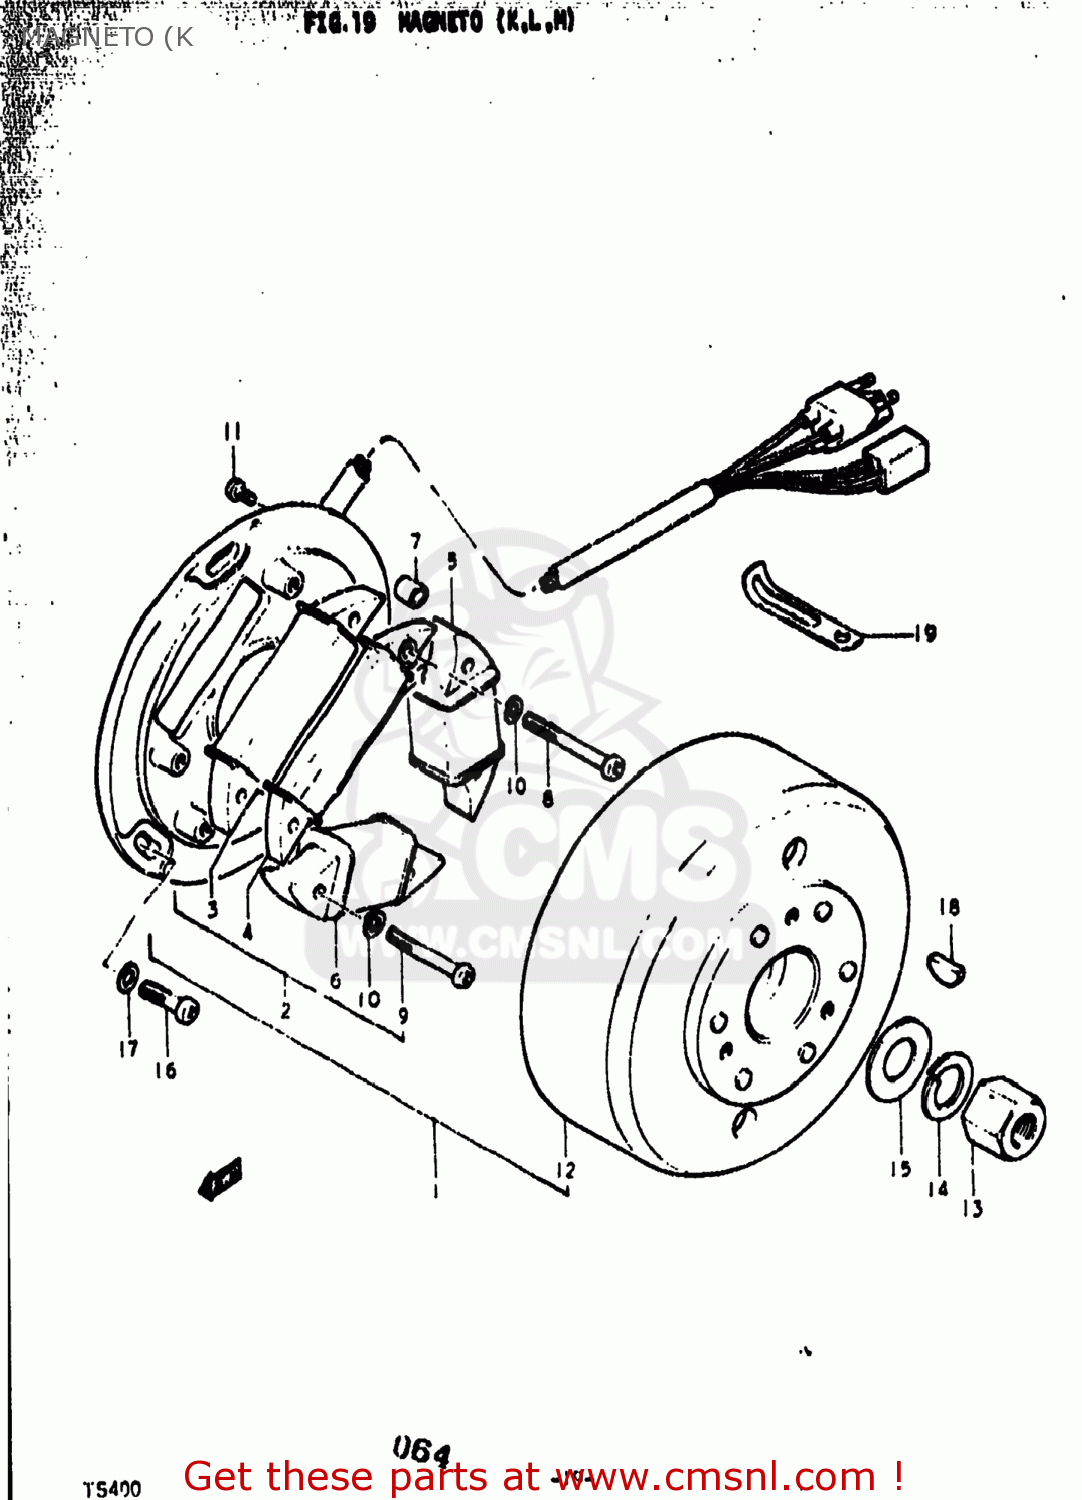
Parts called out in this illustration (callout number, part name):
1	MAGNETO ASSEMBLY
2	STATOR ASSEMBLY
3	COIL
4	COIL,PULSER
5	COIL,LIGHTING
6	COIL,LIGHTING
7	COIL ASSEMBLY,PICK-UP
8	SCREW 5X35
9	SCREW
10	LOCK WASHER
11	SCREW
12	ROTOR,FLYWHEEL
13	NUT
14	LOCK WASHER
15	WASHER(14X27X3)
16	SCREW
17	WASHER
18	KEY 4MM
19	CLAMP
